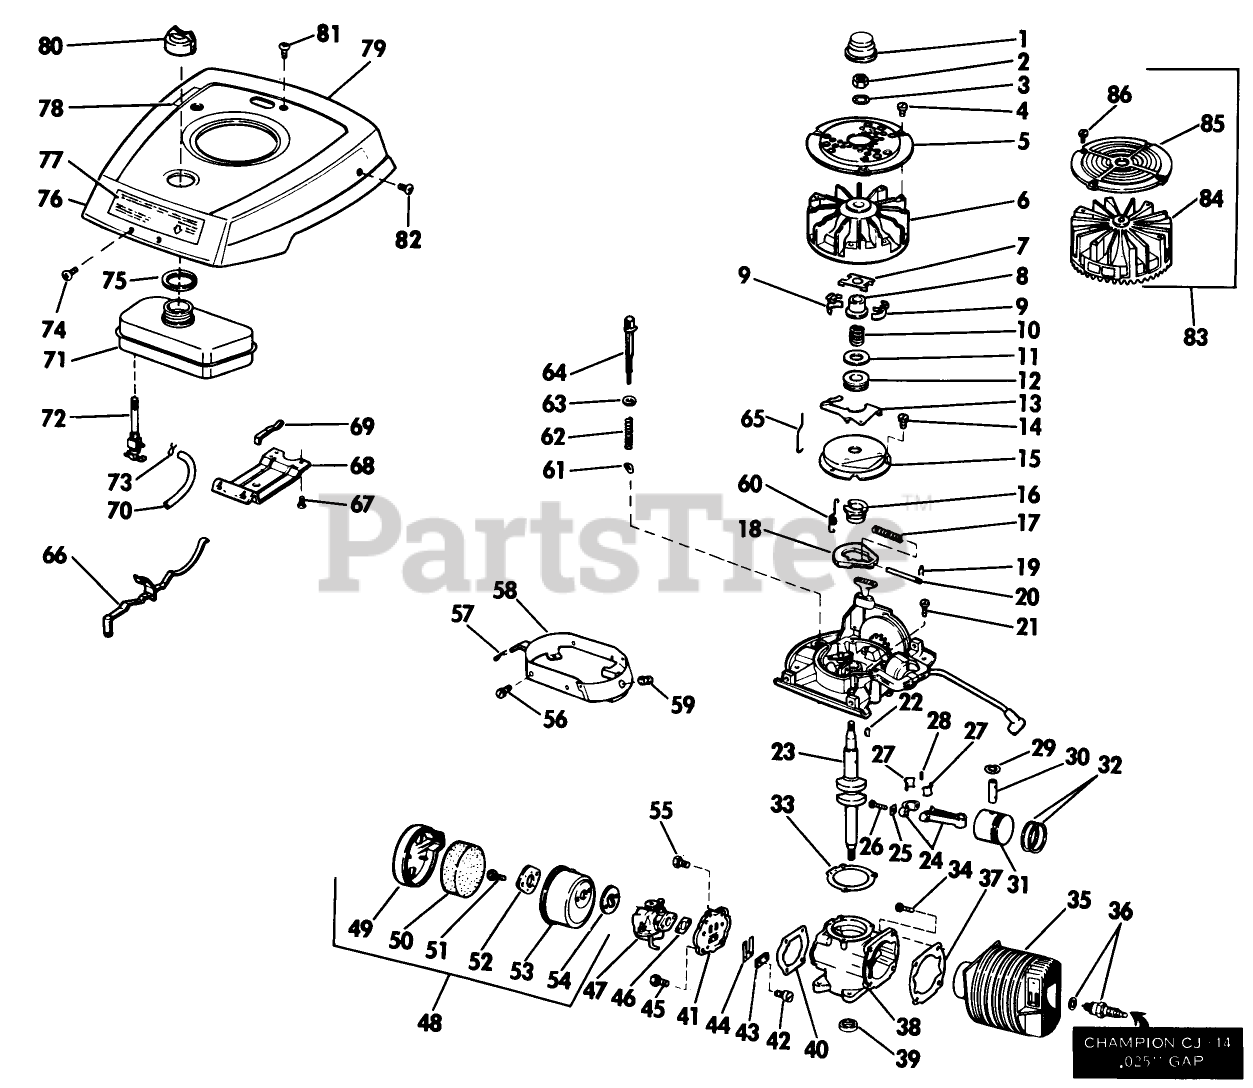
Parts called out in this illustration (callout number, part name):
4	SCREW F
8	COLLAR S
10	SPRING S
12	THRUST COLLAR S
13	LEVER-GOVERNOR S
14	SCREW S
15	DUST COVER S
16	SPARK ADV. S
17	SPARK ADV. SPRING S
18	FLYWEIGHT S
19	SPARK ADJ. SPRING
20	PIN,SPARK ADV. S
27	LINER ASM
29	RING-RETAINING
33	GASKET S
36	Spark Plug and Gasket
37	GASKET S
41	REED PLATE AY. S
43	PLATE-BACKUP, REED
45	SCREW S
46	GASKET S
49	CHAMBER AY S
50	AIR FIL.ELEM S
51	SCREW S
53	FILTER CHAMBER S
54	GASKET S
55	SCREW S
56	SCREW S
59	NUT-CLIP
62	SPRING S
66	SPEED CONTROL
67	SCREW S
70	GAS LINE
72	VALVE&SCREEN SM
73	CLAMP - HOSE S
81	SCREW F
82	SCREW S
83	Flywheel Screen Assy.
84	FLYWHEEL S
86	SCREW F
